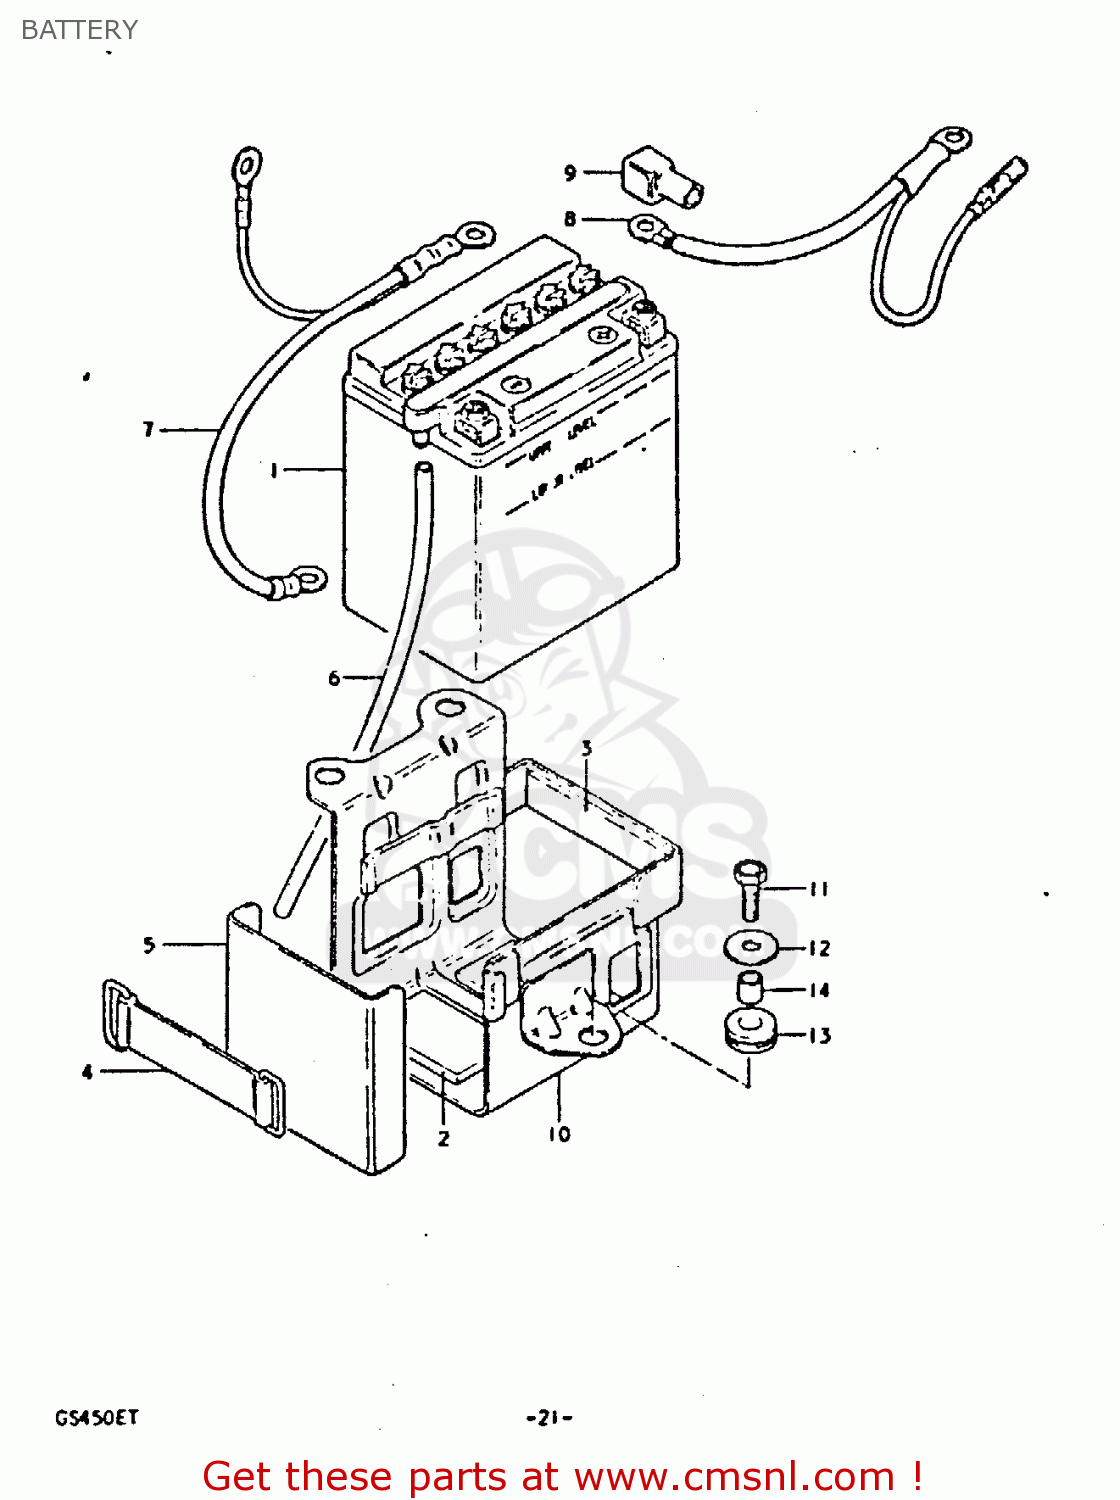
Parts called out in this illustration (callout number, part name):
1	BATTERY ASSY (12V)
2	CUSHION,BATTERY
3	PROTECTOR,20X9
4	BAND
5	COVER,BATTERY
6	HOSE,BATTERY EXHAUST
7	CORD,BATTERY MINUS
8	WIRE,BATTERY PLUS
9	CAP,TERMINAL
10	HOLDER,BATTERY
11	BOLT
12	WASHER
13	CUSHION
14	SPACER (6.1X9X9)
